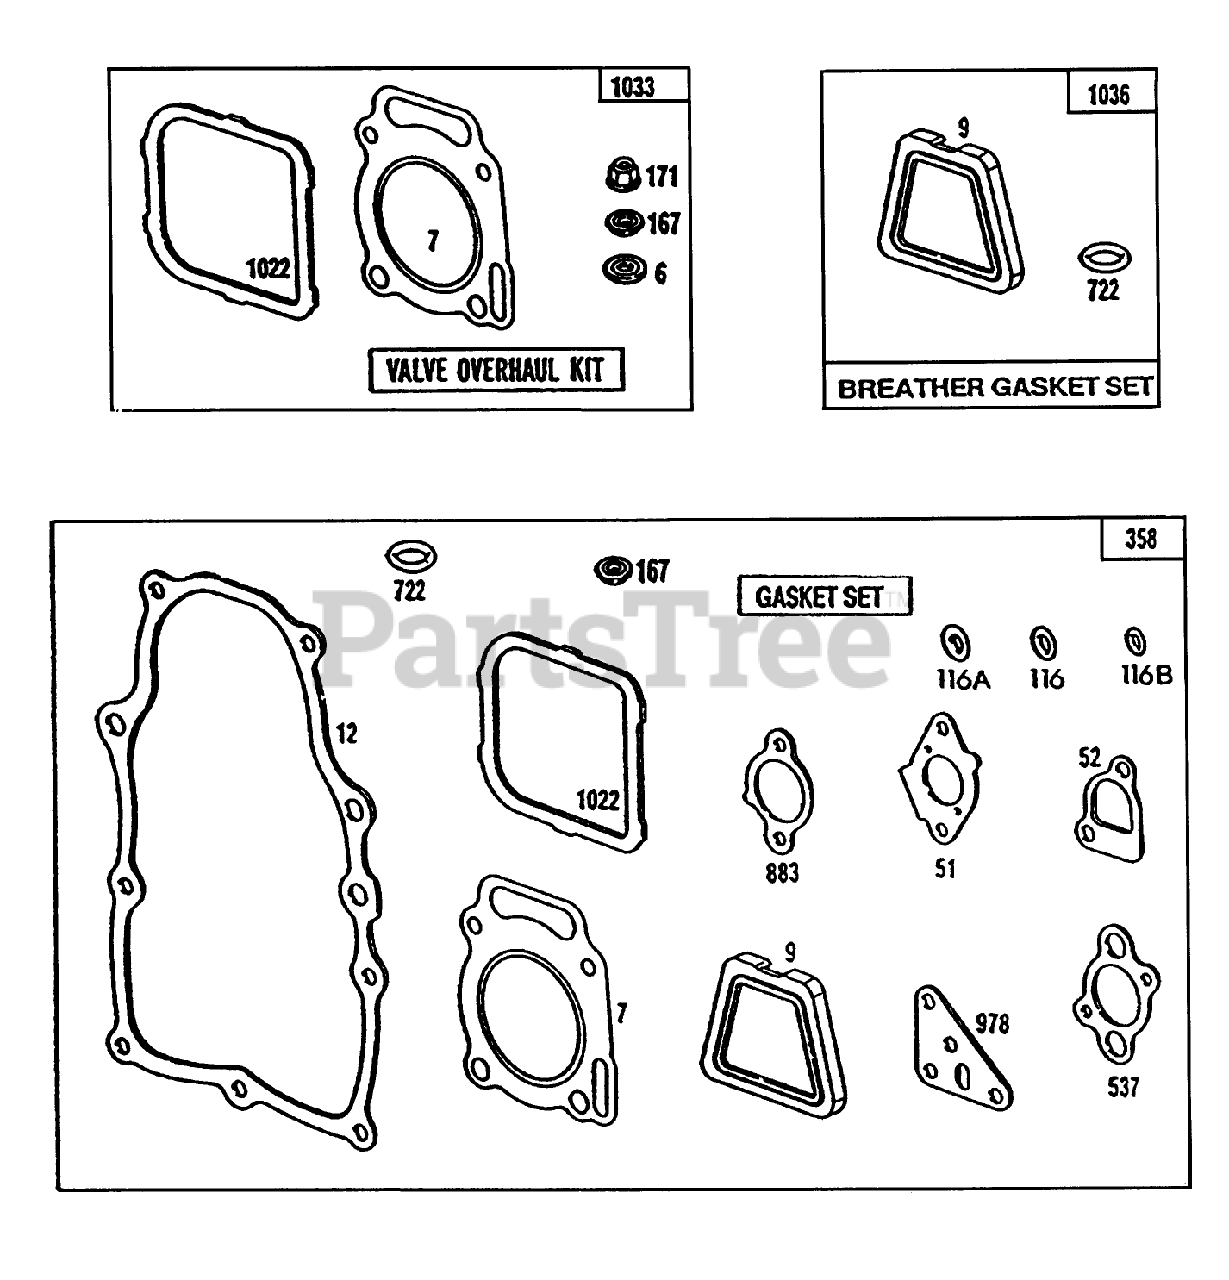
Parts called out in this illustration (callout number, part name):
6	BRIGGS-805193
7	ANGLE - BOOM MNT, RH
9	BRIGGS-805379
12	BRIGGS-805312
51	BRIGGS-805149
52	BRIGGS 805023
116	BRIGGS-805058
116A	BRIGGS-805198
116B	Kit-Gasket Sealing
167	BRIGGS-805420
171	BRIGGS 805019
358	BRIGGS-807989
537	BRIGGS 805655
883	GSKT-EXHST MANIFOLD
978	BRIGGS 805250
1022	BRIGGS-805028
